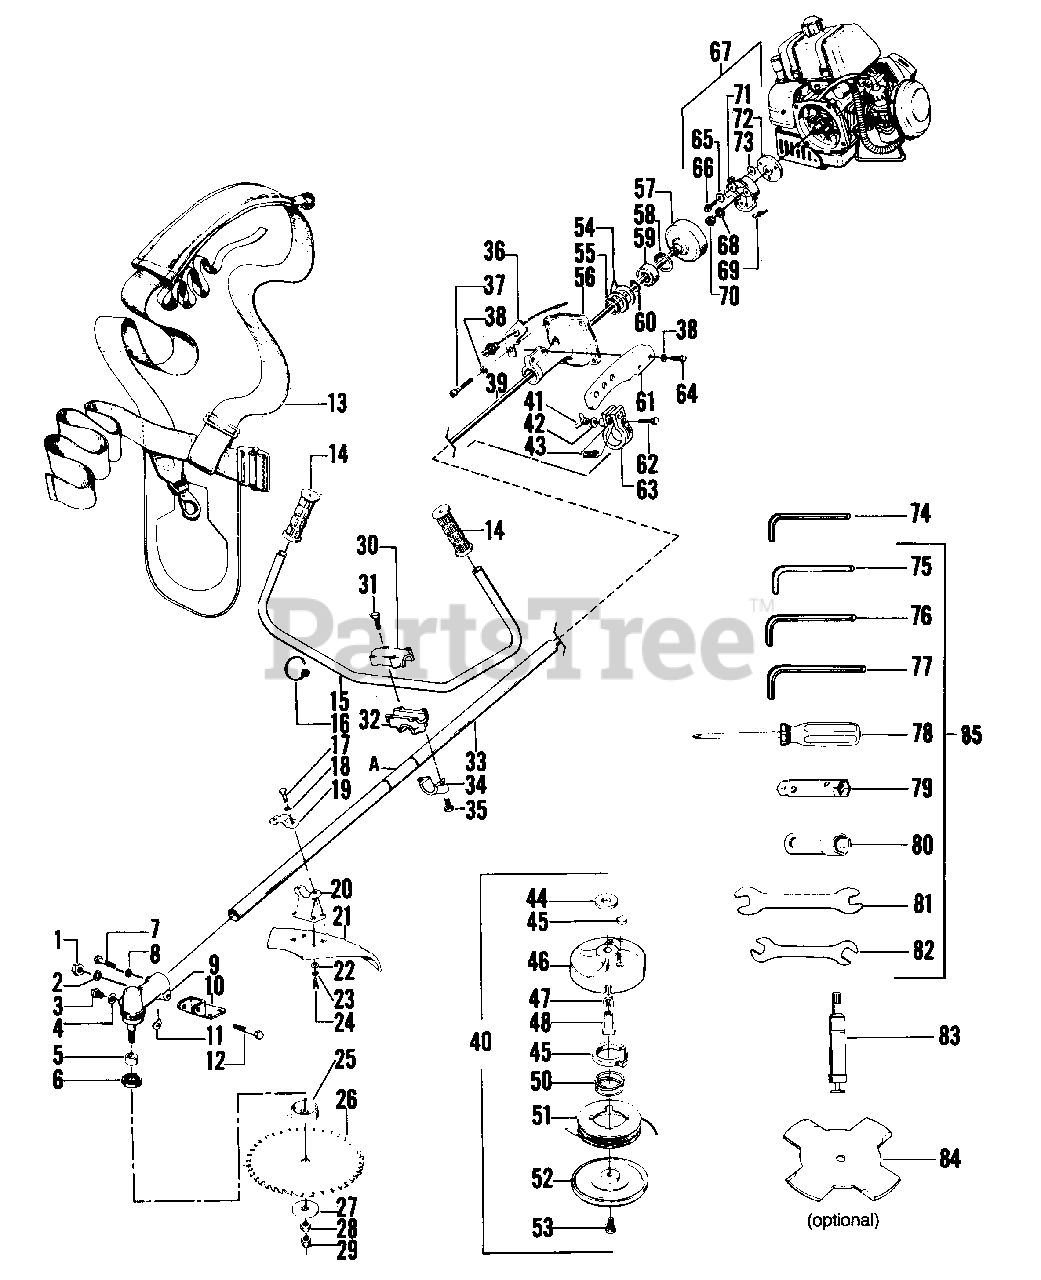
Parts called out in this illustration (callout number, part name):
1	Nut - 6mm - Housing (Gear Box)
2	Lockwasher - 6mm - Housing (Gear Box)
3	Plug - Oil Hole
5	Collar Shaft
6	Oil Seal
7	Bolt, Housing - 6 x 12mm
8	Lockwasher, Bearing Housing
9	Gear Box Assembly
10	Bracket Shield/Gear Box See Service Ref.1
11	Filter, Washer
12	Bolt, Gear Box - 6mm x 34mm
13	Shoulder Strap Assembly
14	Grip, Handlebar
15	Handiebar
16	Throttle Cable Tie Strap
17	Bolt, Bracket Shield Assembly
18	Washer, Bracket Shield Assembly
19	Upper Cap Bracket, Shield Assembly
20	Lower Bracket, Shield Assembly
22	Flat Washer
23	Lock Washer
24	Screw, Shield
25	Upper Blade Adaptor
26	10" Brush Blade
27	Blade Adaptor (Lower)
30	Upper Cap, Handle Clamp Assembly
31	Screw, Handlebar Clamp Assembly
32	Middle Block, Handlebar Clamp Assembly
33	Drive Shaft Housing Assembly
34	Lower Cap, Handlebar Clamp Assembly
35	Screw, Handlebar Clamp Assembly
36	Run/Stop Switch Assembly
37	Bolt, Motor Leg
38	Lockwasher
39	Drive Shaft
40	Cutting Head Ass'y, (Incl. #44-53 & 74)
41	Wing Nut
45	Release Button Ass'y, (Incl. Lock Ring)
47	Line Saver
48	Drive Adaptor
51	Spool w/line
52	Cover, Cutting Head
53	Screw, Cover
54	Spacer, Clutch Housing
55	Snap Ring, Clutch Housing
56	Clutch Housing
57	Drum, Clutch
58	Snap Ring, Clutch Housing
59	Bearing, Clutch Housing
60	Snap Ring, Clutch Housing
61	Bracket, Shoulder Harness
63	Clamp - Tension
64	Bolt, Shoulder Harness Bracket
65	Washer, Clutch Shoe
66	Bolt, Clutch Shoe
67	Clutch Assembly (Inc.65,66,69,71,72,73)
68	Washer, Clutch Assembly
69	Spring, Clutch
70	Nut, Clutch Assembly
71	Clutch Shoe
72	Clutch Rotor
73	Washer, Clutch Shoe
74	Allen Wrench - Cutting Head
75	Head Removal Tool
76	Wrench - 5 mm Hex
77	Wrench - 4 mm Hex
78	Screwdriver - Phillips
79	Wrench - 10 mm & 12 mm Socket
80	Wrench - Spark Plug Socket
81	Wrench - 14 mm & 17 mm
82	Wrench - 8 mm & 10 mm
83	Grease Gun
84	Weed Blade (Optional)
85	Tool Kit (Incl.#75-82)
A	Decal - Handlebar Locator
